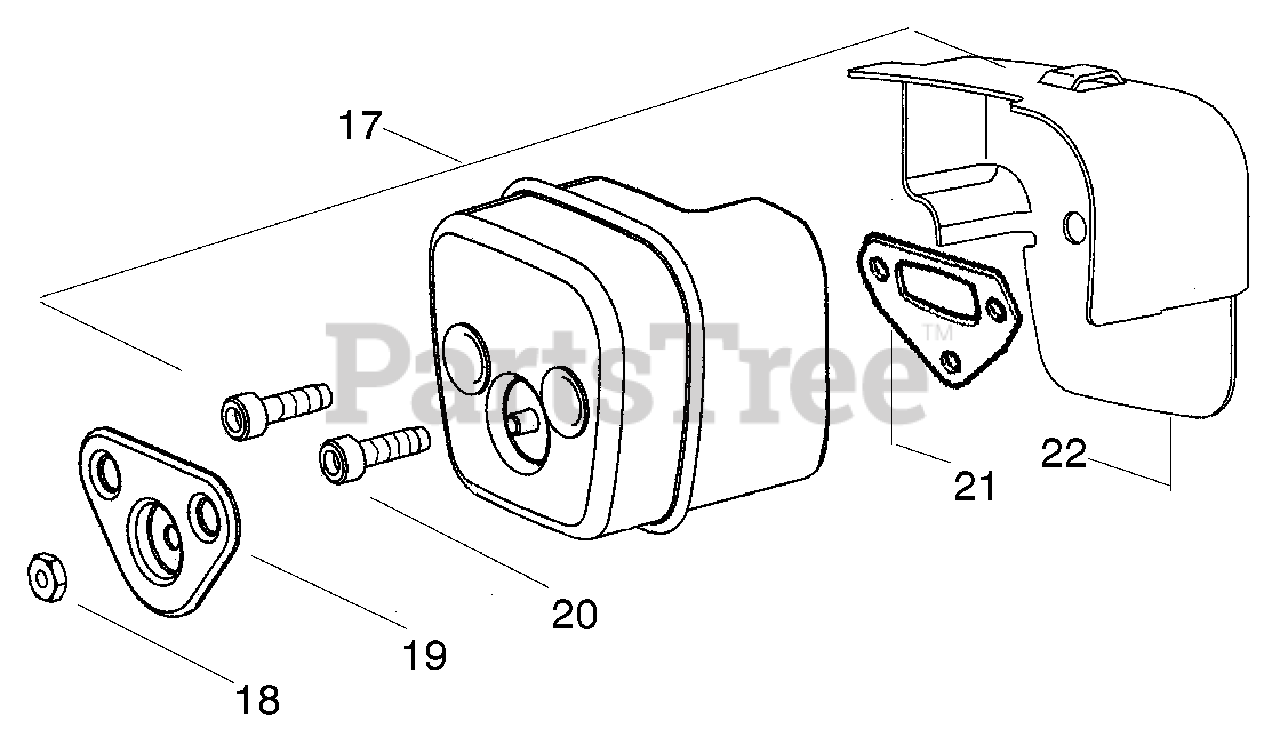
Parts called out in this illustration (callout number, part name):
17	Kit-Muffler
18	Nut-Brass
19	Cover-Bolt
20	Bolt-Muffler
21	Gasket-Muffler
22	Backplate-Muffler
